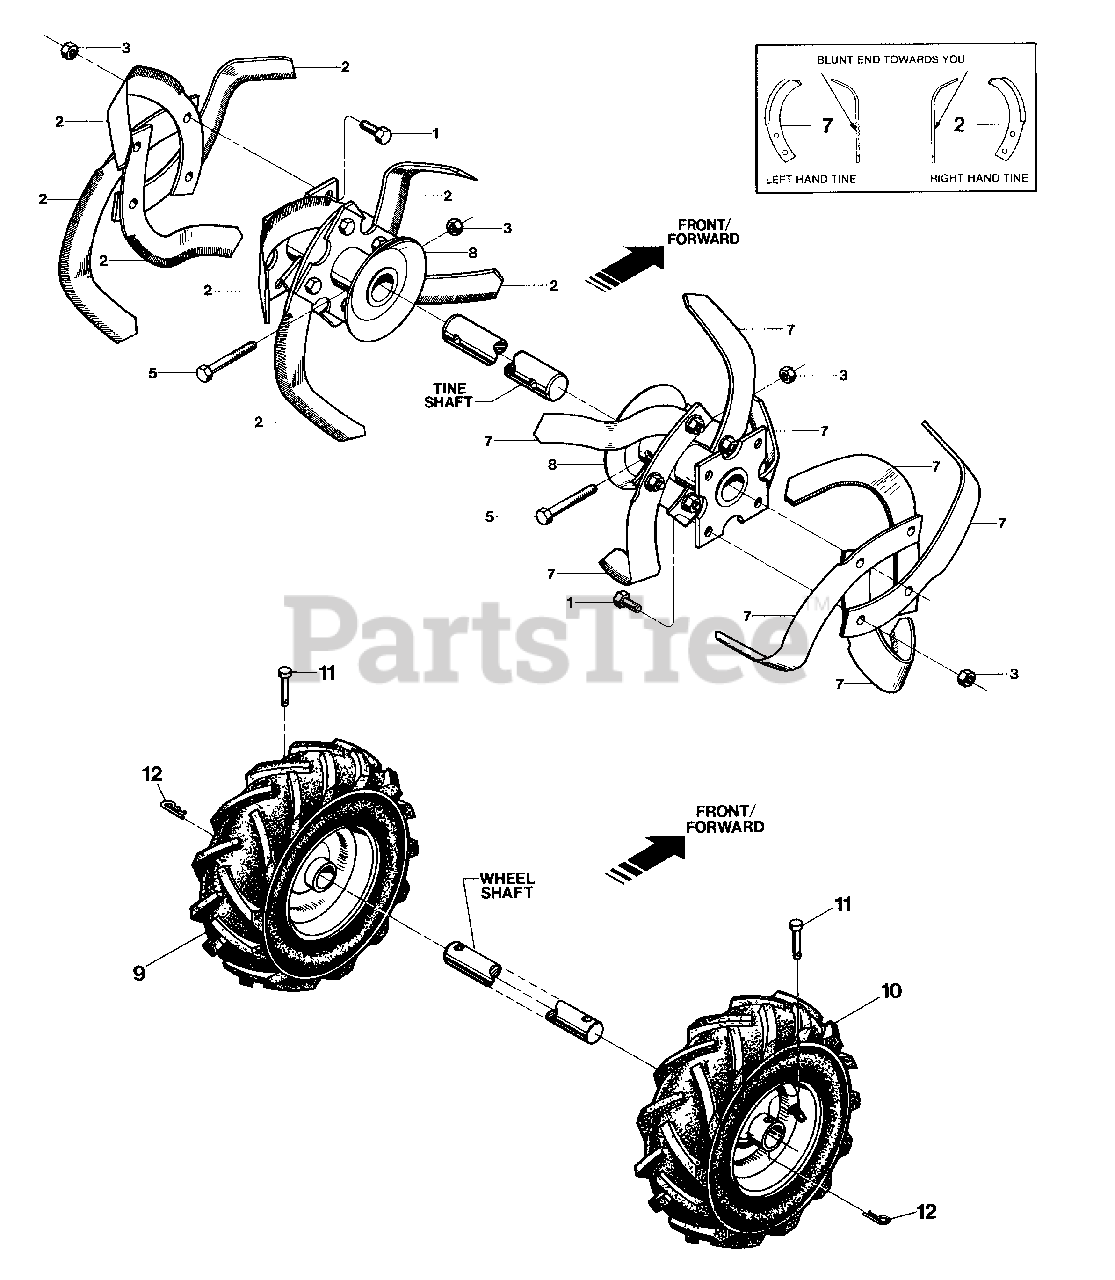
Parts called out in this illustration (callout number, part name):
1	Screw-hex hd., 3/8-16 x 1-1/4
2	Bolo Tine-single, right hand tine
3	Hex Locknut, 3/8-16
5	Screw-hex hd., 3/8-16 x 2, GRADE 8
7	Bolo Tine-single, left hand tine
8	Tine Holder-
9	Wheel & Tire Assy-left side
10	Wheel & Tire Assy-right side
11	Clevis Pin-.312 x 1-3/4 long
12	Hitch Pin
